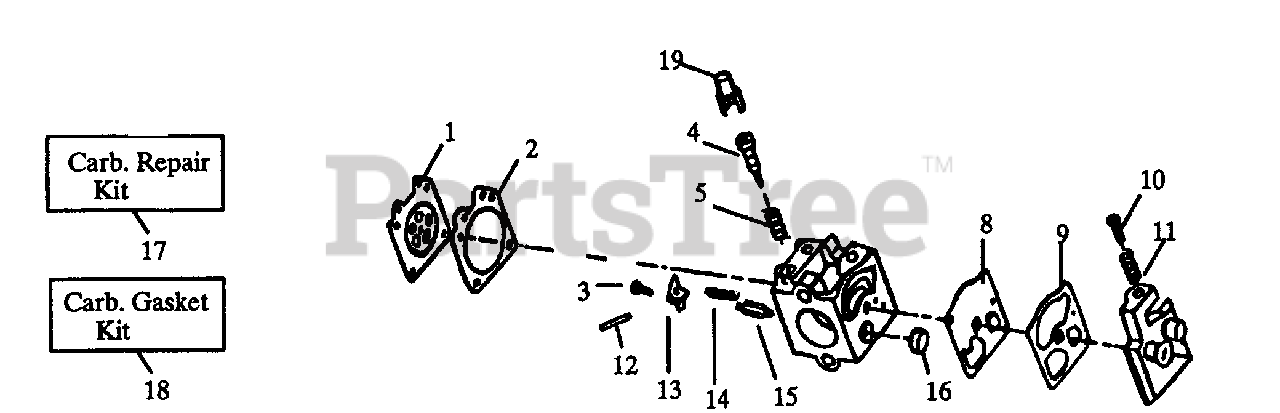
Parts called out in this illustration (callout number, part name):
1	Metering Diaphragm
2	WT-141 - T1
2	WT-141A - T2
3	Metering Lever Pin Screw
4	WT-141 - T1
4	WT-141A - T2
5	WT-141 - T1
5	WT-141A - T2
8	Fuel Pump Diaphragm
9	Fuel Pump Gasket
10	Idle Speed Screw
11	Idle Speed Spring
12	Metering Lever Pin
13	Metering Lever
14	WT-141 - T1
14	WT-141A - T2
15	Inlet Needle Valve
16	Fuel Inlet Screen
17	Carb. Kwik Repair Kit
18	Carb. Gasket/Diaphragm Kit
19	Limiter Cap (Gold)
